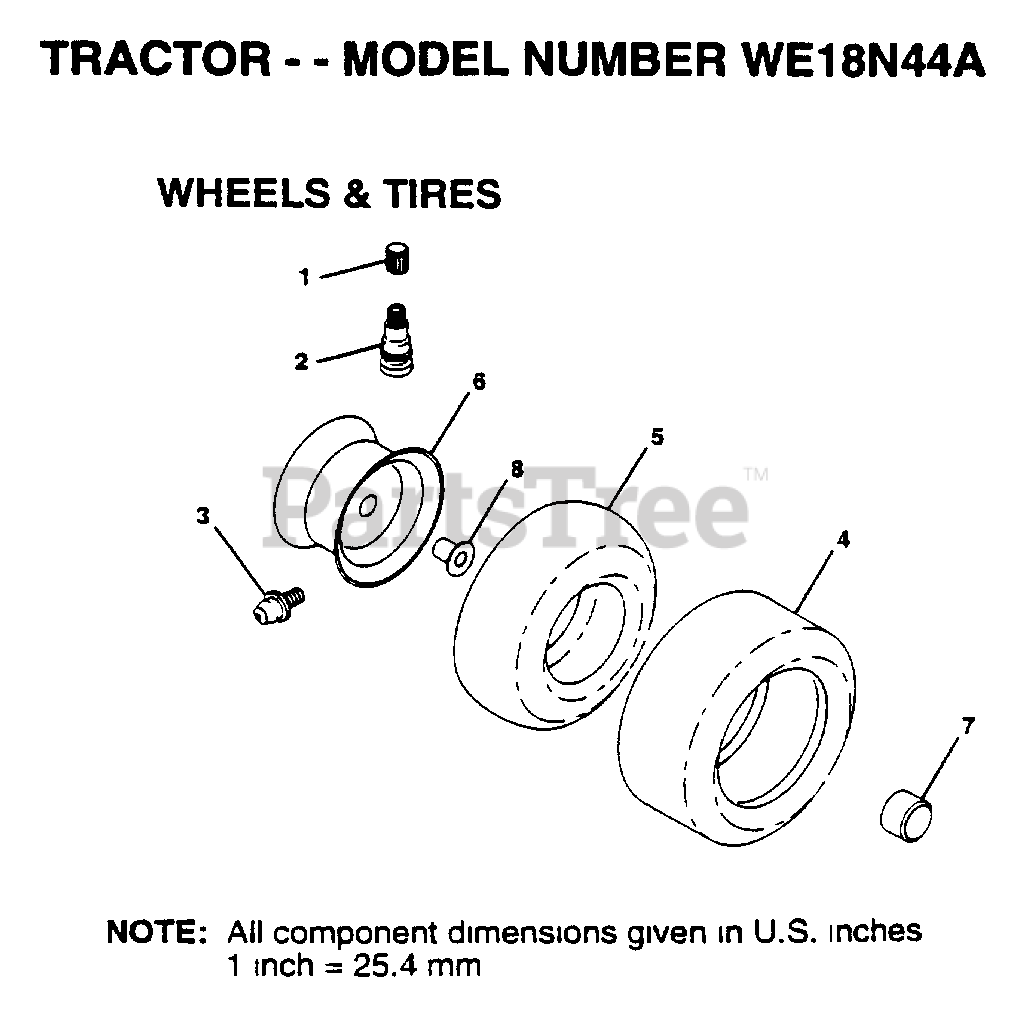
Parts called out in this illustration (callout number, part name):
1	VALVE CAP
2	VALVE STEM LT
3	FITTING LT
5	TUBE.5.3/4.5/6
5	TUBE.23X8/10-12
6	"RIM.FRONT.8"".YEL"
6	"RIM.REAR.12"".LT"
7	HUB CAP
8	"FLANGE, BEARING"
